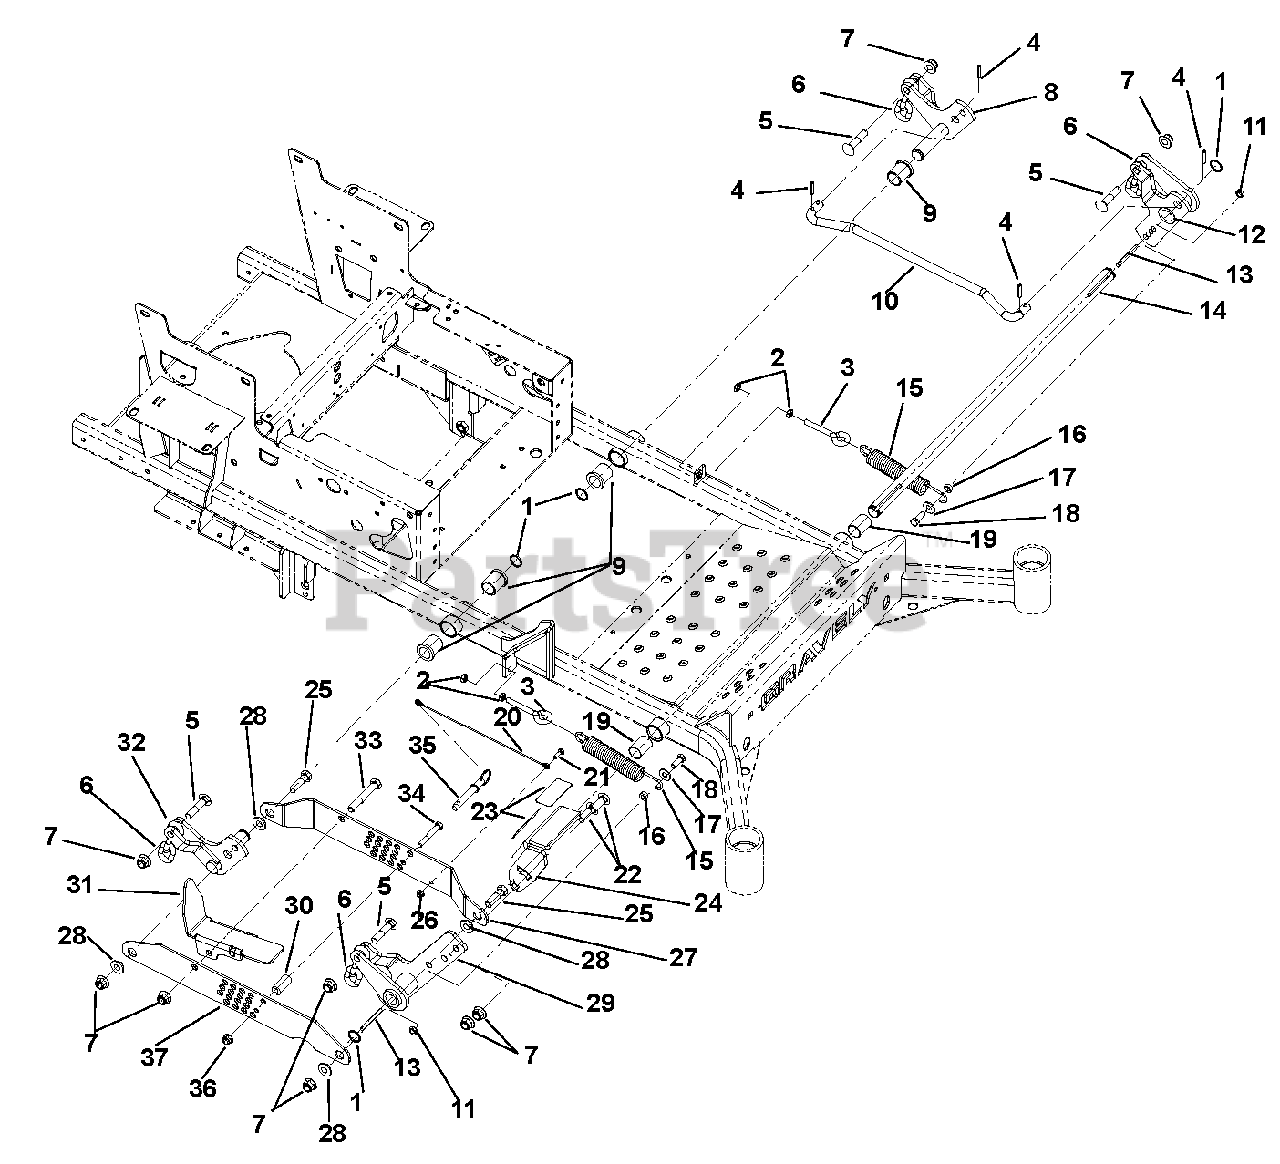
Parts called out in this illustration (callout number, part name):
1	Ring, Retaining External 1.00 x .078
2	Nut, Hex Jam .375-16
3	Bolt, Eye .375-16 x 2.50
4	Pin, Roll .25 x 1.25 Stainless Steel
5	Bolt, Round Head Square Neck .50-13 x 2.25
6	Chain, 3-Link .38 Deck Lift
7	Nut, Locking Nylon Flange .50-13
8	Weldment, Left Hand Rear Deck Lift
9	Bushing, Flange 1.00 x 1.25 x 1.50 x 1.50
10	Rod, Lift Assist 19.35"
11	Nut, Locking Center Jam .375-16
12	Weldment, Front Left Hand Deck Lift
13	Key, Square .25 x 2.50 x .25 SAE
14	Shaft, PT100 Front Mower Lift
15	Spring, Tension .162 x 1.25 x 8.25 Weldment 25
16	Bushing, Sleeve .377 x .624 x .235
17	Washer, Flat Steel .438 x 1.00 x .083
18	Bolt, Hex .38-16 x 1.00
19	Bushing, 1.00 ID x 1.125 OD x 1.50
20	Cable, 12.0 Lanyard, Nylon
21	Bolt, Hex .25-20 x .75
22	Bolt, Round Head Square Neck .50-13 x 1.50
23	Grip, Pedal 1.50 x 3.00
24	Adjustable Foot Lift Pedal, Black
25	Bolt, Hex .50-13 x 1.75
26	Nut, Locking Nylon Flange .25-20
27	RH Lift/Cut Height Bracket, InboardINBD, Black
28	Bushing, Flange .515 x .750 x .395 x 1.120
29	Weldment, Adjustable Deck Foot Lift
30	Spacer, .375 x .750 x 1.54
31	Mechanical Lock-up Weldment, Black
32	Weldment, Right Hand Rear Deck Lift
33	Bolt, Hex .50-13 x 3.25
34	Bolt, Hex .38-16 x 2.50
35	Pin, .50 x 2.00 Usable Length Ball
36	Nut, Locking Nylon Flange .38-16
